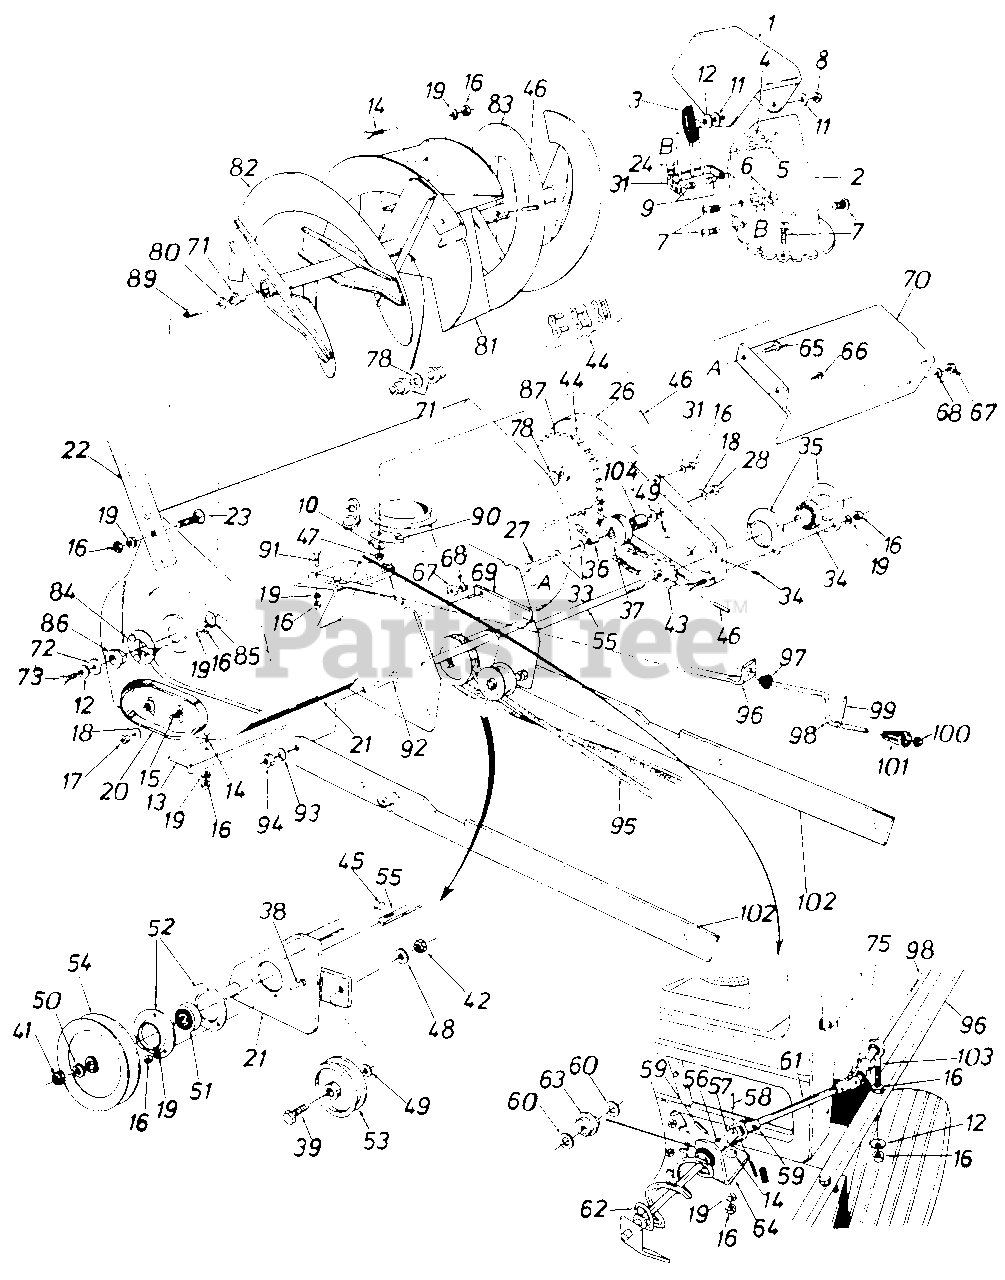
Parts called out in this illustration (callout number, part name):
1	Upper Chute
2	Lower Chute
3	Knob Handle Ass'y.
4	Truss Mach. Scr. 5/16-18 x .75" Lg.
5	Carriage Bolt 5/16-18 x 1.0"
6	Hex Cent. L-Nut 5/16-18 Thd.
7	Truss Mach. Scr. 1/4-20 x .75" Lg.
8	Hex Cent. L-Nut 5/16-18 Thd.
9	Shld. Nut 1/4-20 Thd.
10	Fl.-Wash. 1/4" I.D.
11	Fl.-Wash. .344" I.D. x 1.125"
12	Bell. Wash. .345" I.D. x .88"
14	Carriage Bolt 5/16-18 x .62"
15	Carriage Bolt 3/8-16 x .62"
16	Hex Nut 5/16-18 Thd.
17	Hex Jam Nut 3/8-16 Thd.
18	Bell. Wash. .40 I.D. x .88"
19	L.-Wash. 5/16" I.D.
20	Slide Shoe
21	Spiral Hsg. Ass'y.-36"
22	Guide Blade
23	Carriage Bolt 5/16-18 x .62"
24	Extension Spring
26	Chain Guard Ass'y.
27	Hex Bolt 3/8-16 x 2.00 Lg.
28	Hex Inst.-Nut 3/8-16 Thd.
33	Fl.-Wash. .385" I.D. x .87" O.D.
34	Ball Brg. .75" I.D.
35	Flangette
36	Spacer .375" I.D. x .60" O.D.
37	Fl.-Idlere w/Flanges 1.875
38	Hex Sems Bolt 5/18 x .75" Lg.
39	Hex Bolt 3/8-16 x 1.75" Lg.
41	Hex Jam Nut 3/4-10 Thd.
42	Hex Jam Nut 3/8-16 Thd.
43	Sprocket Ass'y. 14 Teeth
44	4420 Chain x 1/2" Pitch * 77 Links
45	#61 Hi-Pro Key 3/16 x 5/8"
46	Spring Pin Spir. 5/16" Dia. x 1.75" 4.
47	Hex L-Nut 1/4-20 Thd.
48	L.-Wash. 3/8" I.D.
49	FI.-Wash. .406" I.D. x 1.25"
50	Spring L.-Wash. 3/4" I.D.
51	Self-Aligning Brg.
52	Flangette
53	Ider Puiley
54	5/8 V-Pulley .75" I.D. x 6"
55	Drive Shaft Ass'y.
56	Joint Brkt. Ass'y.
57	Joint Block
58	Oval Head Rivet
59	Spiral Pin 1/8" Dia.
60	Fl.-Wash. .385" I.D. x .62"
61	Chute Crank Ext. Rod
62	Chute Crank Ass'y. R.H.
63	Plastic Bushing .380" I.D.
64	Chute Crank Brkt.
65	Hex Bolt 1/4-20 x .62" Lg.
66	Hex Wash. S-Tap Scr. 1/4-20 x .50" Lg.
67	Hex Nut 1/4-20 Thd.
68	L.-Wash. 1/4" I.D.
69	Belt Cover
70	Drive Shaft Cover
71	Plastic Bushing
72	Washer .39" I.D. x 1.75" O.D.
73	Hex Bolt 5/16-18 x .88" Spec.
75	Cotter Pin 3/32" Dia.
78	Fl.-Wash. 1.03" I.D. x 1.62"
80	Fl.-Wash. 1.0" x 1.75"
85	Snap Ring for 1.50" Shaft
86	Flange Brg. w/flats 1.00" I.D.
87	Sprocket Hub Ass'y. 40 Teeth
89	Spiral Axle
90	Chute Flange Keeper
91	Hex Bolt 5/16-18 x 1.5" Lg.
92	Hex Bolt 1/2-13 x 1.25" Lg.
93	L.-Wash. 1/2" I.D.
94	Hex Nut 1/2"-13 Thd.
95	"V"-Belt
98	Chute Crank 34.5" Lg.
99	Roll Pin .12 Dia. x .63
100	Push Nut 3/8" Rod
101	Knob Black
102	Linkage Arrn
103	Eye Bolt 5/16-18 x 3.0" Lg.
104	Idler Spacer
